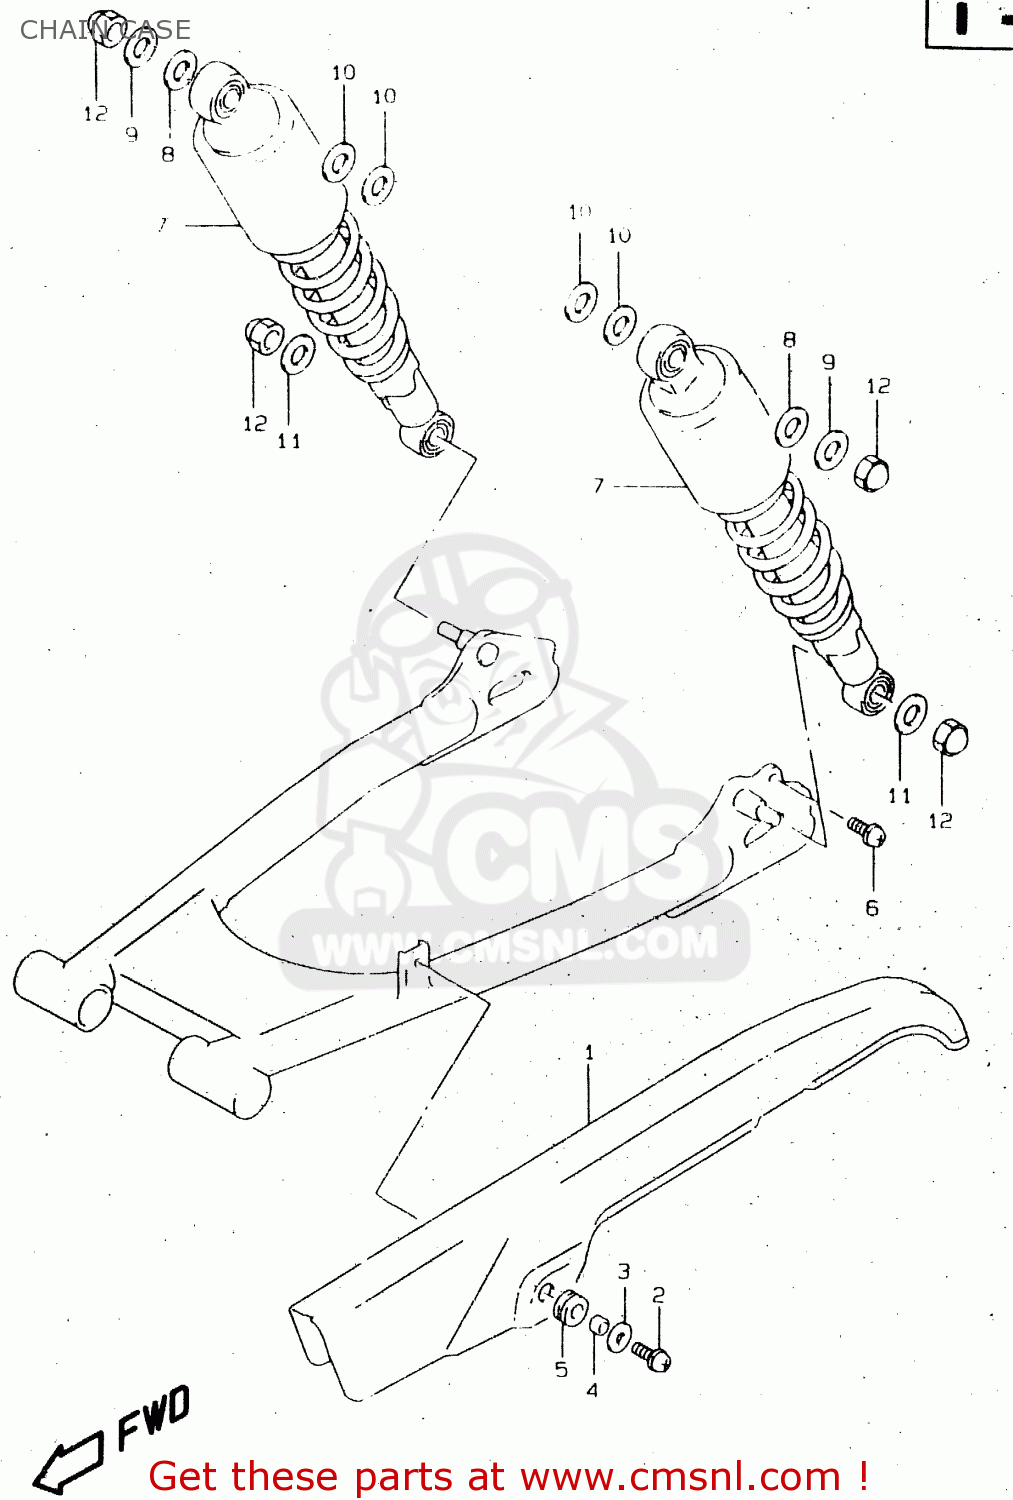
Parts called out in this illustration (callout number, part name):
1	CASE,CHAIN
2	SCREW
3	WASHER(6.5X20X1.2)
4	SPACER(6.5X9X7)
5	CUSHION
6	SCREW
7	ABSORBER ASSY,RR SHOCK
8	WASHER (10.5X24X2.3)
9	WASHER
10	WASHER
11	WASHER (10.5X24X2.3)
12	NUT
